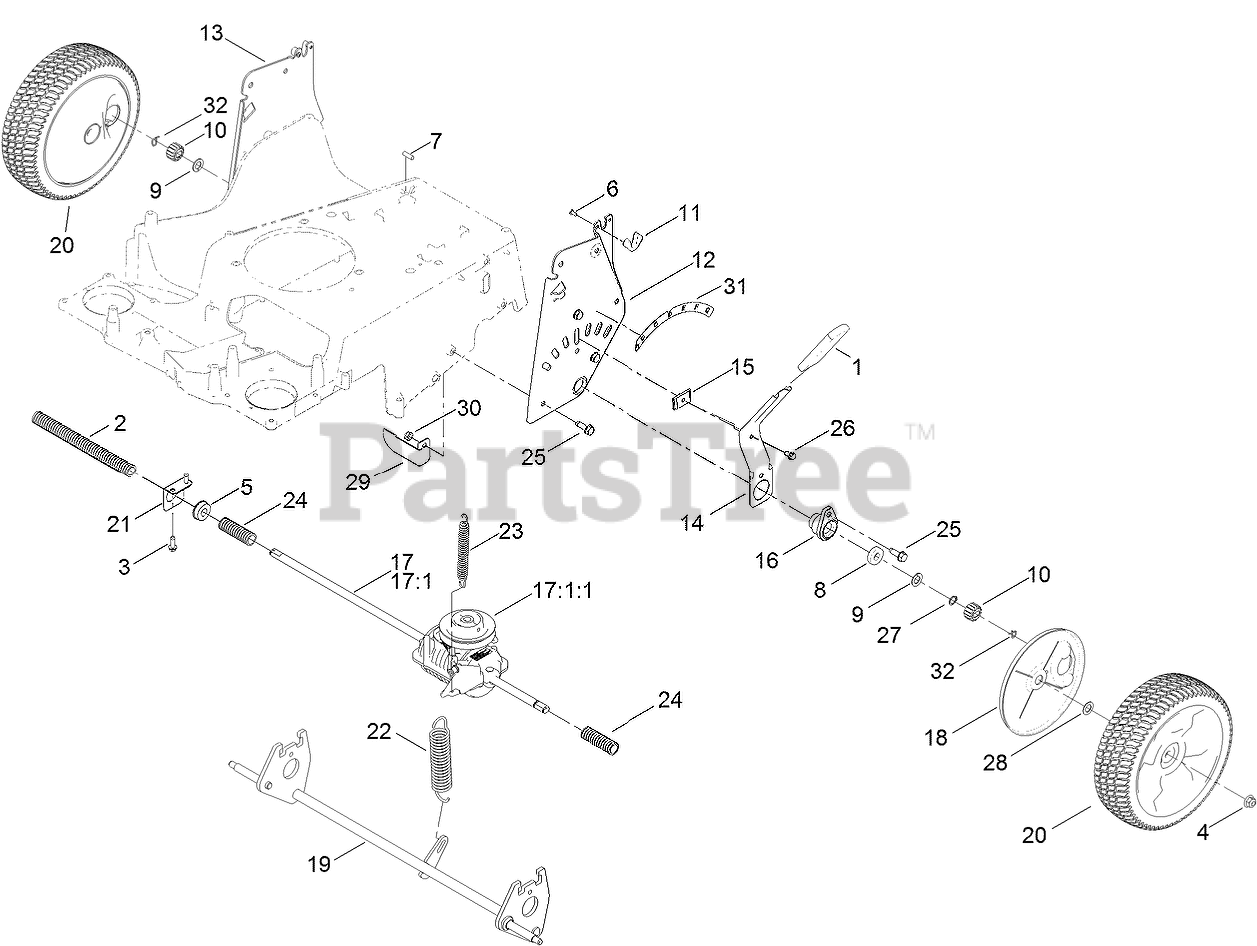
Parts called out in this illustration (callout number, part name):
1	GRIP-LEVER, LIFT
2	CONDUIT-CONVOLUTED
3	SCREW-HWHTF
4	NUT-HF, NI
5	BEARING-BALL
6	Screw-PPH
7	PIN-STOP
8	BEARING-BALL
9	WASHER-THRUST
10	GEAR-PINION, 15T
11	ANCHOR-BAG
12	PLATE-HOC, LH
13	PLATE-HOC, RH
14	ARM-SPRING, REAR
15	KEY-SPRINGARM
16	RETAINER-BEARING
17	TRANSMISSION KIT
17:1:1	TRANSMISSION PULLEY KIT
18	COVER-GEAR
19	AXLE-REAR
20	10 INCH WHEEL GEAR ASM
21	MOUNT-BEARING
22	SPRING-EXTENSION
23	SPRING-EXTENSION
24	CONDUIT-CONVOLUTED
25	SCREW-HWHTF
26	SCREW-HWH
27	RING-RETAINING
28	WASHER-PLAIN
29	BRACKET-STOP
30	NUT-LOCK, NI
31	DECAL-HOC, REAR
32	PIN-SNAP
